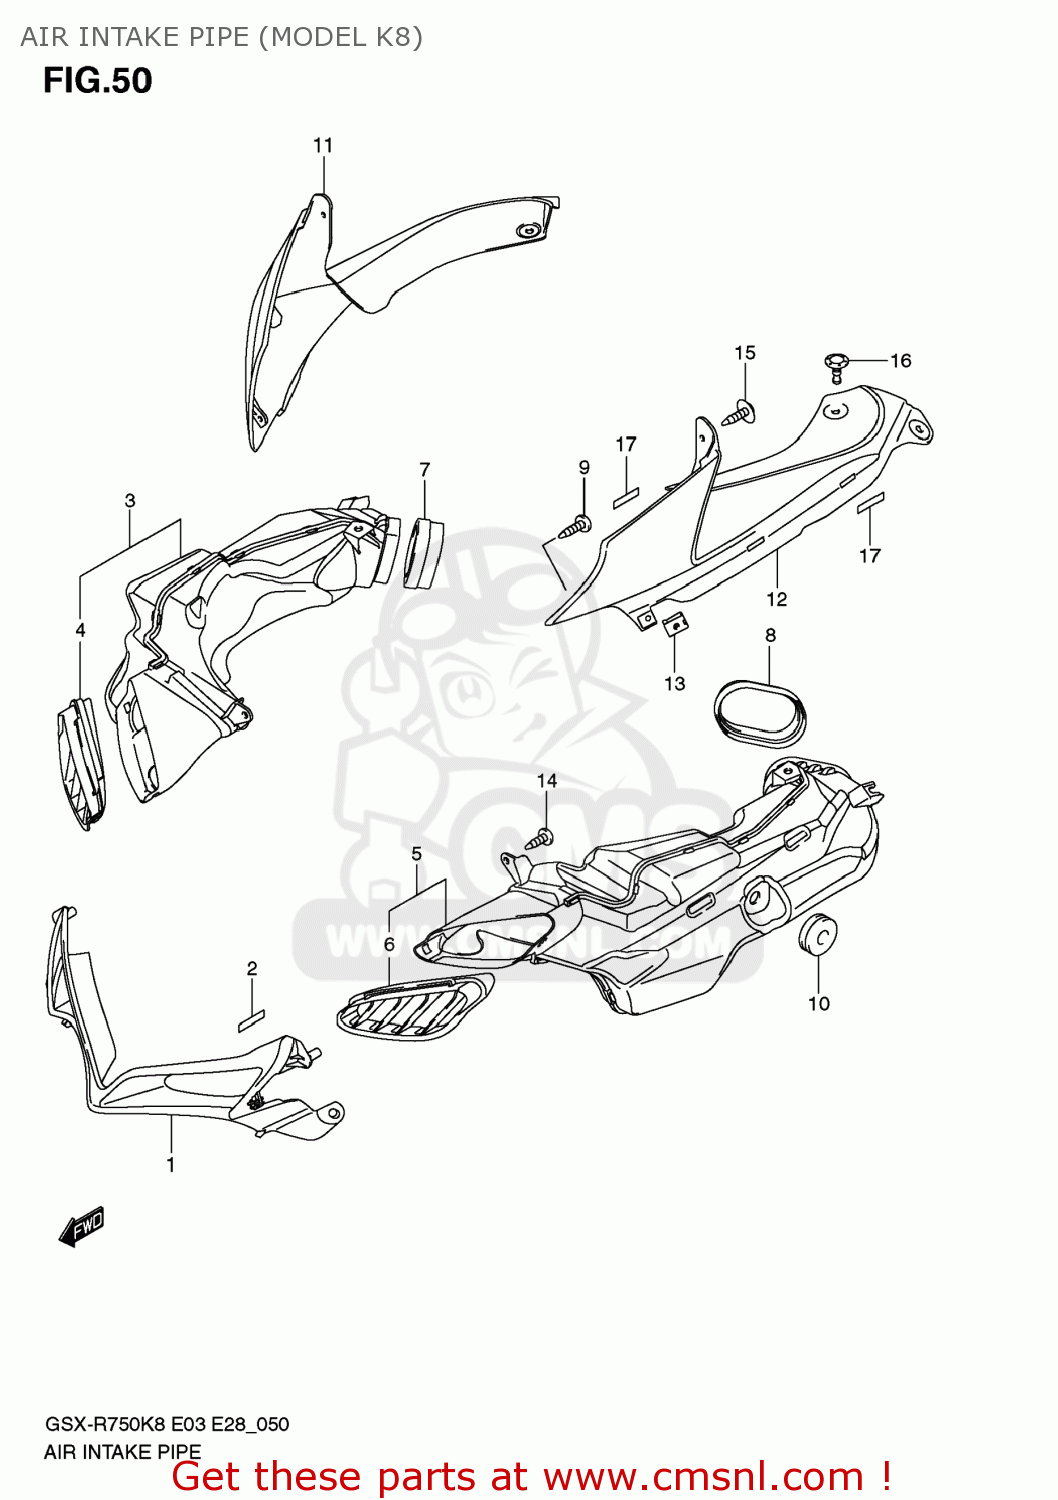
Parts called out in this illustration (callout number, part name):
1	COVER,INTAKE
2	TAPE(6X25X0.13)
3	PIPE ASSY,AIR INTAKE,R
4	NET,INTAKE PIPE,R
5	PIPE ASSY,AIR INTAKE,L
6	NET,INTAKE PIPE,L
7	MOLDING,AIR INTAKE,R
8	MOLDING,AIR INTAKE,L
9	SCREW
10	CUSHION
11	COVER,INTAKE,R
12	COVER,INTAKE,L
13	NUT
14	SCREW
15	SCREW(5X12)
16	CLIP
17	TAPE(6X25X0.13)
